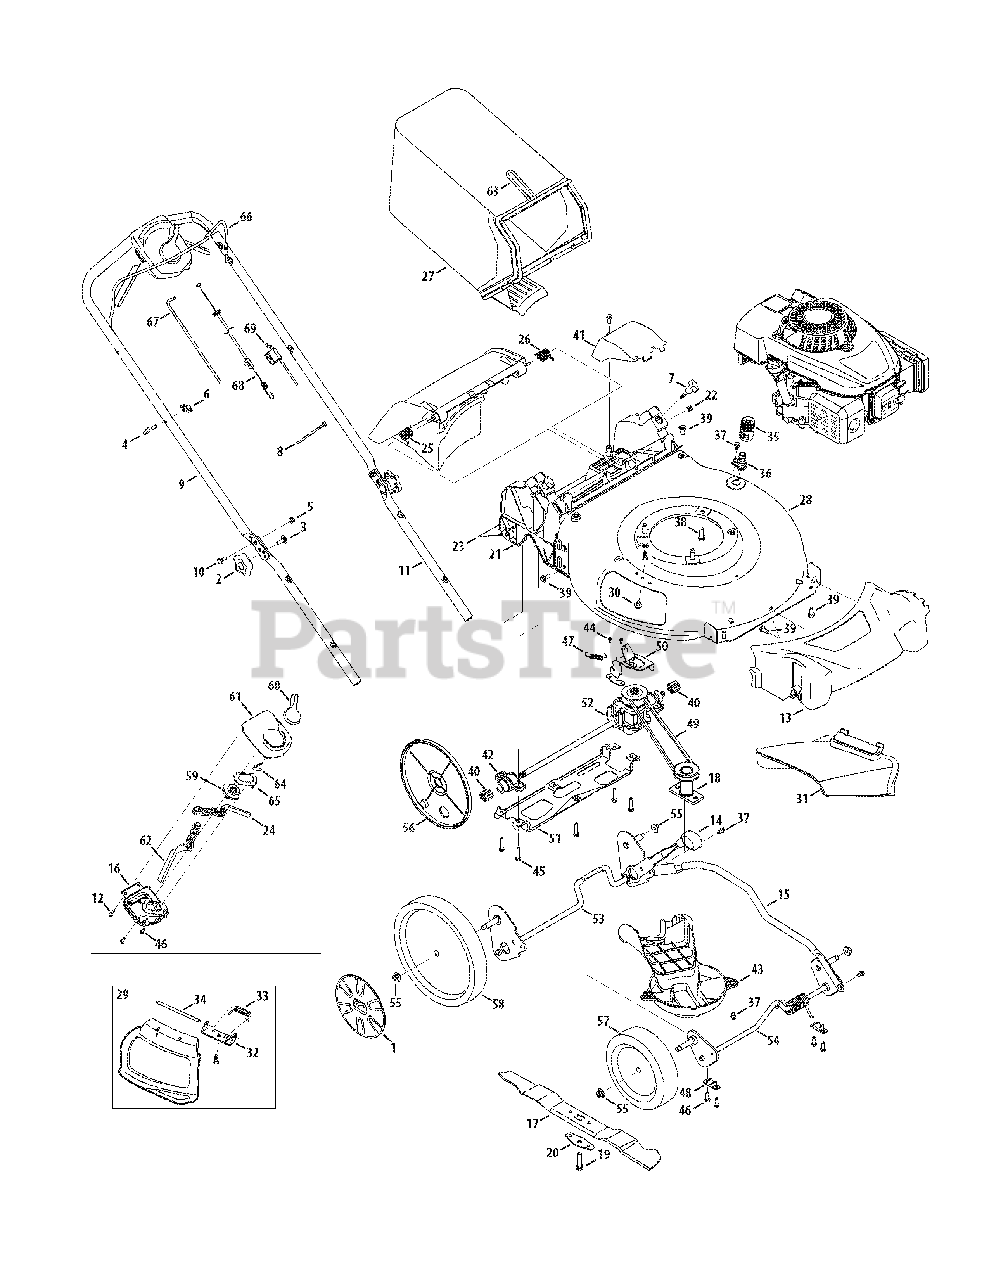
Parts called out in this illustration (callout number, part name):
1	Hubcap - Front
1	Hubcap - Rear
2	Wing Knob
3	Carriage Screw ,5/16-18
4	Rope Guide
5	Nut, Flange Lock, 1/4-20
7	Wing Knob
8	Cable Tie
9	Upper Handle
10	Shdr. Screw, .375 x .126 x 1/4-20
11	Lower Handle
12	Scr., Shldr, 1/4-15 x .970
13	Front Cover
14	Adjustment Knob
15	Tube, Link
16	Lower Housing
17	Mulching Blade
18	Blade Adapter
19	Screw, 3/8-24 x 1.50
20	Blade Bell Support
21	Rear Discharge Door Assembly
22	Nut, Sq., 1/4-20
23	Trail Shield
24	Control Lever LH
25	Torsion Spring - RH
26	Torsion Spring - LH
27	Grass Bag
29	Mulch Plug (Incl. 32-34)
31	Side Discharge Chute
32	Chute Deflector Bracket
33	Torsion Spring
34	Hinge Pin
35	Water Nozzle Adapter
36	Water Nozzle
37	Scr., Shldr., 1/4-20 x .50
38	Screw, tt, 3/8-16 x 1.00
39	Screw, 5/16-14 x .750
40	Spur Gear, 9T
41	Transmission Cover
42	Bearing Assembly
43	Engine Baffle
44	Screw, Hex Washer, .159 x .43
45	Screw, 1/4-15 x 1.25
46	Screw, 1/4-15 x .750
47	Exten. Spring, 2.675
48	Bush., Block
49	V-Belt
50	Transmission Bracket
51	Rear Support Bracket
52	Transmission Assembly
53	Rear Hgt. Adjust./Axle Assembly
54	Front Axle Assembly
55	Flange Lock Nut, 3/8-16
56	Wheel Dust Cover
57	Front Wheel, 8 x2
58	Rear Wheel, 11 x 2
59	Speed Adjust Actuator
60	Speed Selec Lever
61	Upper Housing
62	Control Lever RH
63	Grass Catcher Frame
64	Spring
65	Cable Adjust Plate
66	Blade Control
67	Drive Cable
68	Speed Adjustment Cable
69	Control Cable
